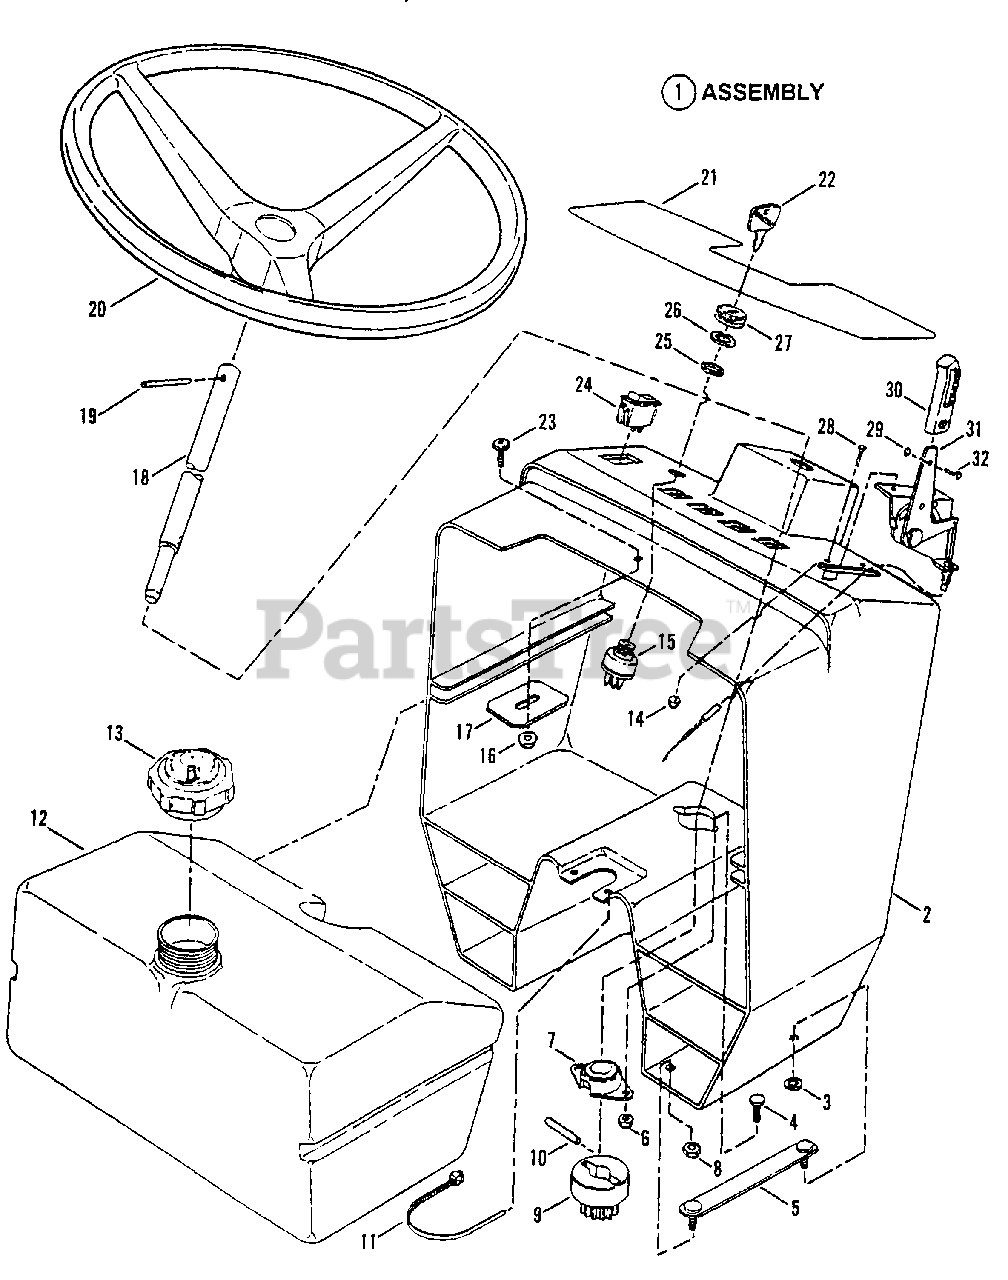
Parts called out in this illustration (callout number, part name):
1	ASSEMBLY, Console
2	CONSOLE
3	RETAINER
4	SCREW, 1/4-20 x 3/4" Hex Head Cap, Grade 5
5	ASSEMBLY, Strap-Clinch Stud
6	NUT, 1/4-20 Hex Nyloc
7	ASSEMBLY, Flange Bearing
8	NUT, 5/16-18 Hex Center Lock
9	GEAR, Pinion, Steering Shaft
10	PIN, Dowel, 1/4 x 1 1/4"
11	TIE, Wire
12	ASSEMBLY, Fuel Tank
13	CAP, Fuel Tank
14	NUT, #10-24 Hex Nyloc
15	KEYSWITCH
16	NUT, 5/16-18 Hex Flange Lock
17	BRACKET, Hood Latch Catch
18	SHAFT, Steering
19	ROLL-PIN
20	STEERING WHEEL
21	DECAL, Console
22	KEY, Switch (With Cover)
23	SCREW, 5/16-18 x 5/8" Truss Head, Torx
24	SWITCH, Lights
26	NUT, 5/8-32 Hex
27	BEZEL
28	SCREW, #10-24 x 5/8" Machine
29	NUT, #8-32 Hex
30	HANDLE, Throttle Control
31	CONTROL, Throttle, 44.6" Long
32	SCREW, #8-32 x 3/8" Cross-Recessed, Fillester Head
